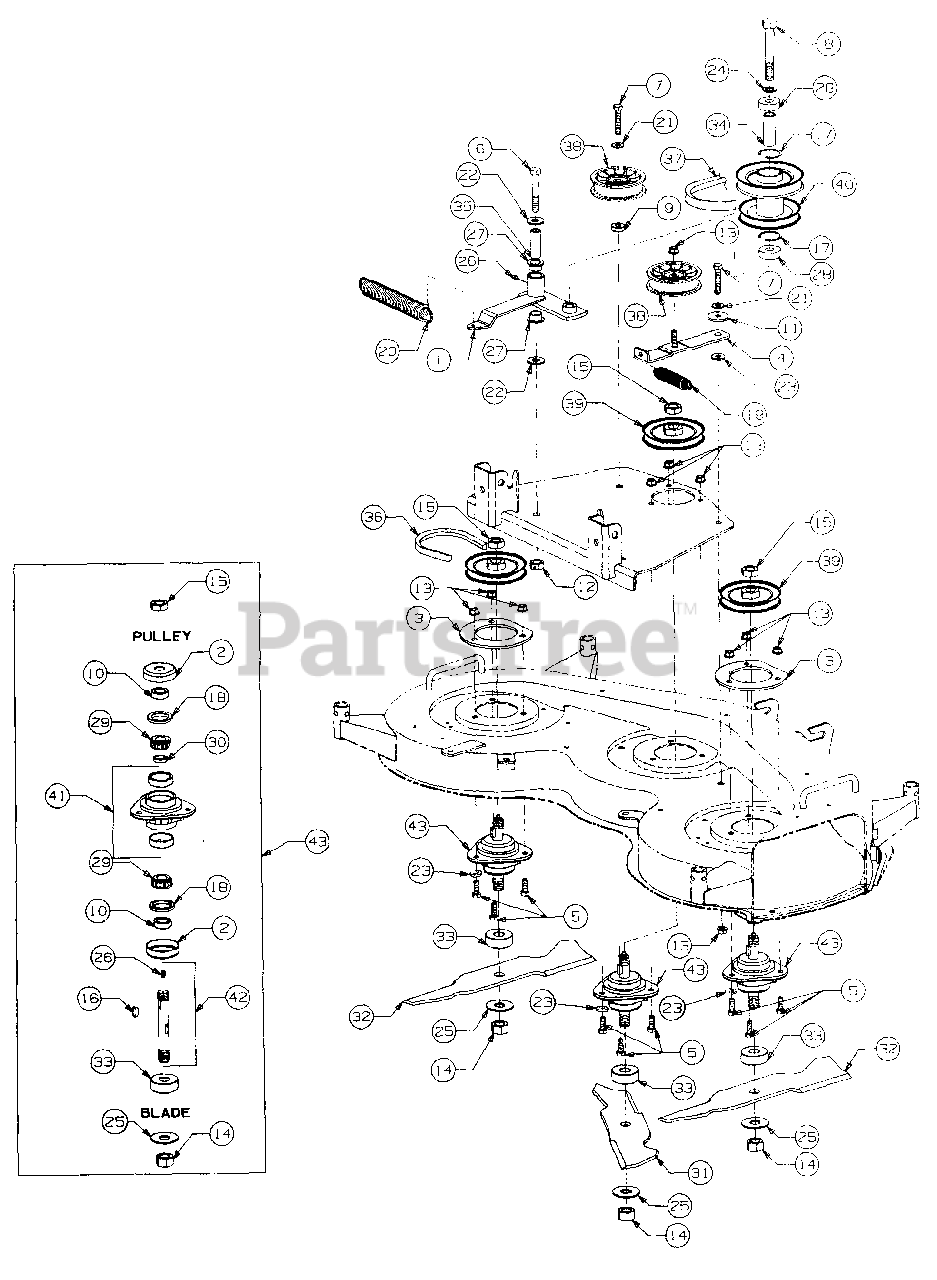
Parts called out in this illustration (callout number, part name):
2	Cup, Spindle
3	Plate, Spindle Mounting
6	Screw, Hex Cap, 1/2-20 x 3 GR8
7	Screw, Hex Cap, 3/8-16 x 2 GR5
8	Screw, Hex Cap, 5/8-18 x 4.25 GR5
9	Spacer, .380 ID x 1 OD x .32
10	Spacer, .755 ID x 1.25 OD x .44
11	Spacer, Shoulder
12	Nut, Hex Center Lock, 1/2-20
13	Nut, Hex Flanged Lock, 3/8-16
14	Nut, Hex, 3/4-16 GR8
15	Nut, Hex Jam, 3/4-16 GR5
16	Key, #91 Woodruff, 1/4 x 3/4
17	Snap Ring, Internal
18	Seal, Oil, 1.25 x 1.874 x .25
19	Spring, Extension, .88 OD x 4
20	Spring, Extension, 1.25 OD x 8.15
21	Washer, Bell, .380 x .88 x .105 Thk
22	Washer, Flat, .531 x 1.25 x .1 Thk
23	Washer, Flat, .385 x 1 x .127 Thk
24	Washer, Flat, .63 x 1 x .063 Thk
25	Washer, Flat, .781 x 2 x .105 Thk
26	Fitting, 3/16 Drive Lube
27	Bearing, Flange, 3/4 ID x .53
28	Bearing, Ball, .62 ID x 1.57 x .44 Thk
29	Cone, Bearing
30	Spacer, Bearing
31	Blade, Low Lift, 14.88"
32	Blade, Low Lift, 16.28"
33	Spacer
34	Spacer, Pulley, .635 ID x.88 OD x 2.37
35	Spacer, Idlr Brkt, .51 ID x .75 OD x 2.07
36	Belt, Spindle, A-Section x 103"
37	Belt, PTO, B-Section x 112.4
38	Pulley, Flat Idler, 3.5 OD
39	V-Pulley, 4.62 OD
40	Pulley, Double
41	Housing w/Cups, Spindle
42	Kit, Shaft w/Seal
43	Spindle Assembly, Blade
